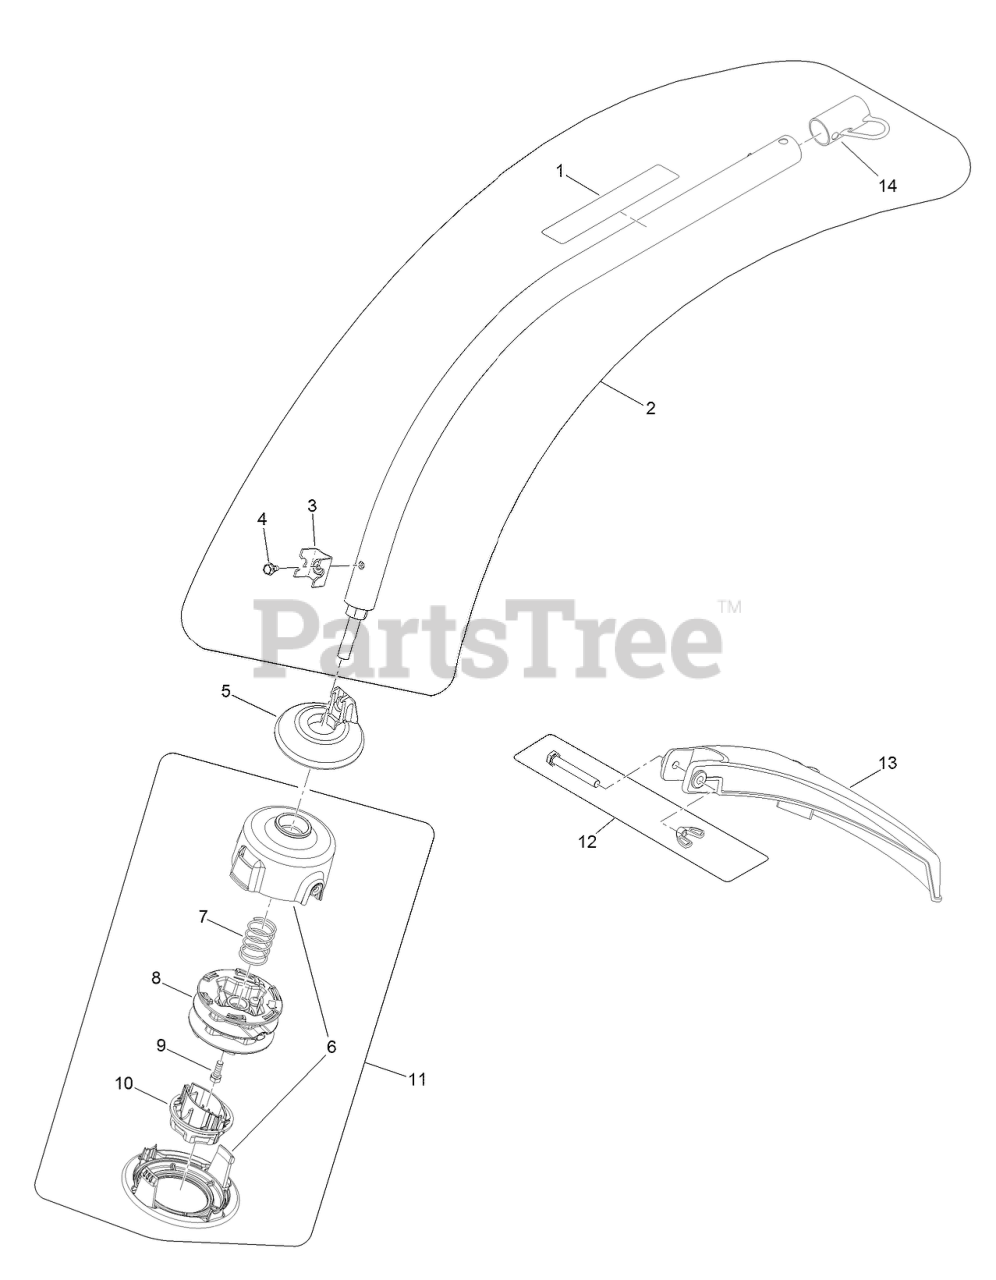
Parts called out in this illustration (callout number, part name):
1	DECAL-WARNING
2	SHAFT ASM
4	SCREW-HWH
5	SHIELD-GRASS
6	HOUSING-STRINGHEAD
7	SPRING-COMPRESSION
8	SPOOL ASM
10	KNOB-BUMP
11	SPOOL HEAD ASM
12	HARDWARE KIT
13	GUARD-SHIELD, GRASS
14	CAP-HANGER
